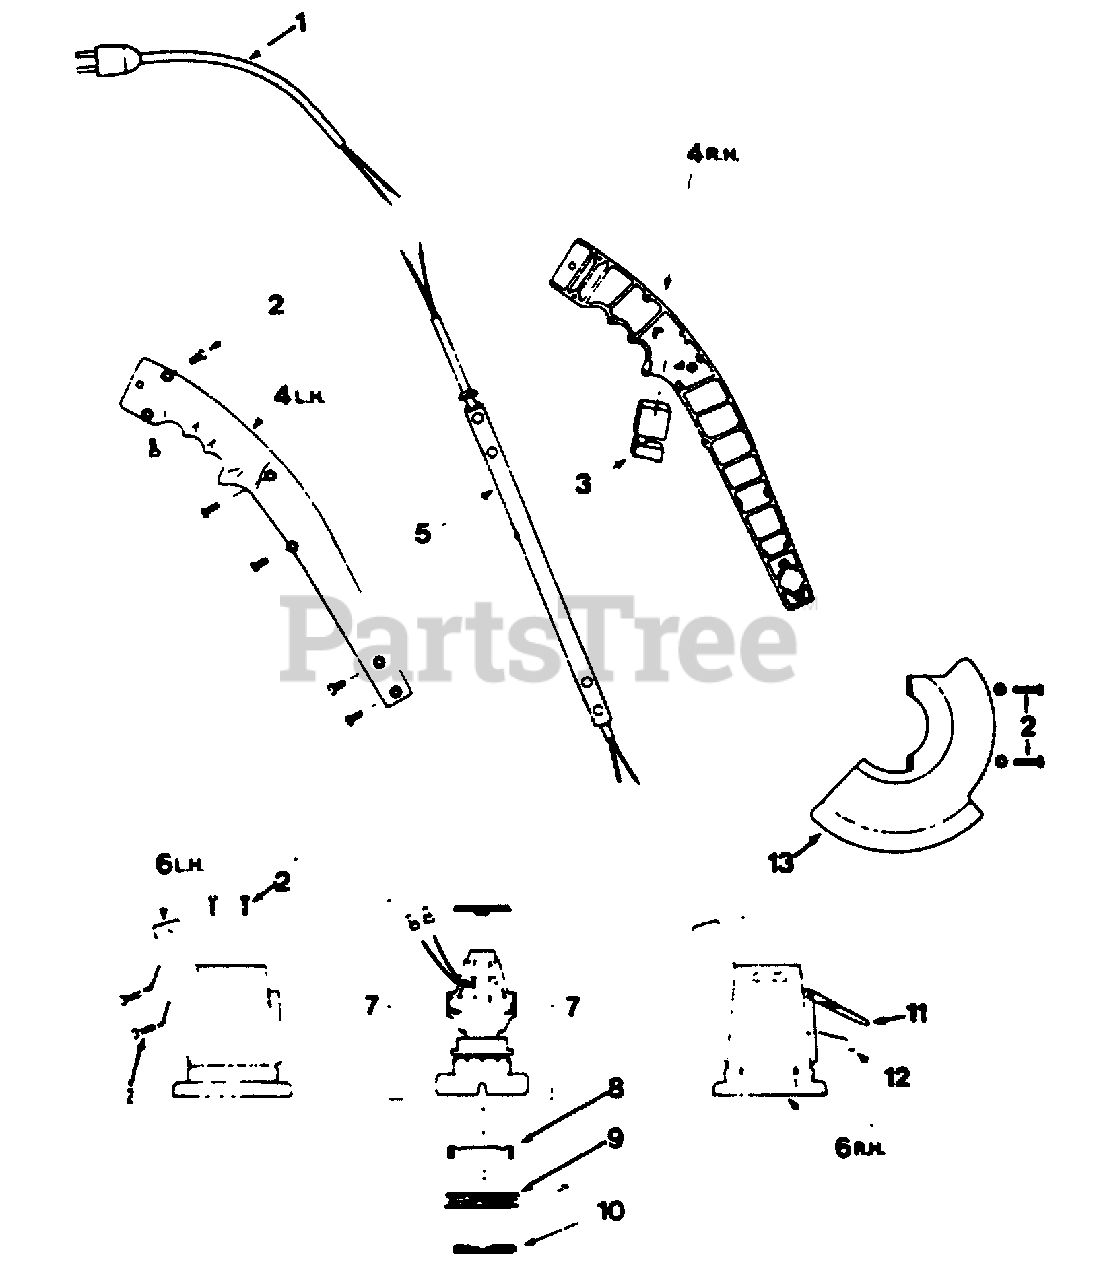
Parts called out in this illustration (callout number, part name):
1	POWER CORD PIGTAIL
4	HANDLE SET
5	HANDLE TUBE (obsolete)
6	MOTOR HSNG. ASSY.
8	LINE SAVER
9	SPOOL WOUND
10	COUNTERBALANCE
11	CLIP OFF LEVER
12	CLIP OFF BLADE
